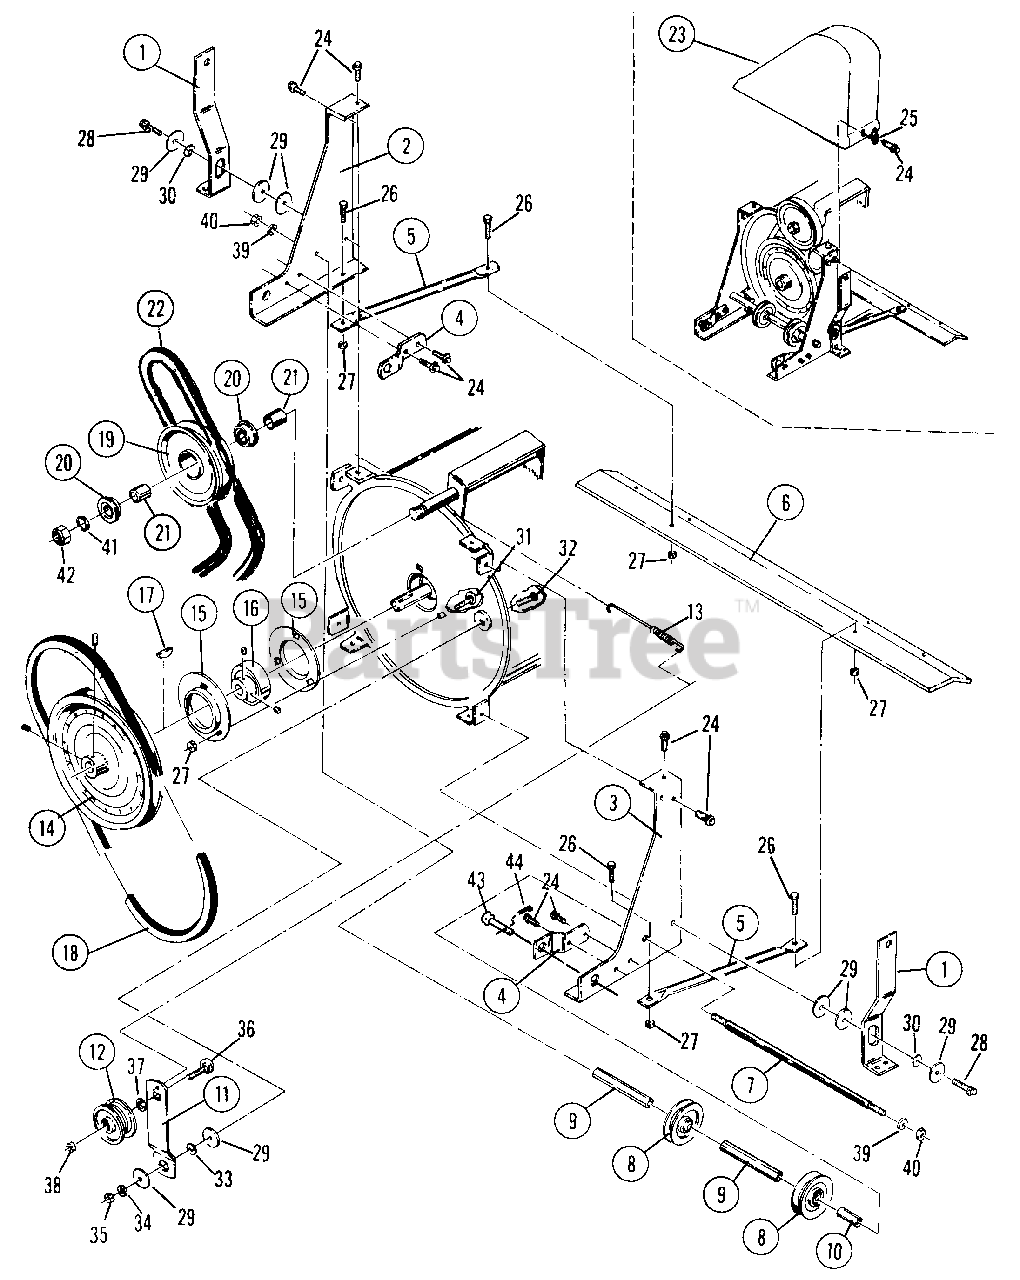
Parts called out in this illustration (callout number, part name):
1	LINK, Lift
2	BRACKET, Left Side Mounting
3	BRACKET, Right Side Mounting
4	BRACKET, Lower Mounting
6	BAR, Stiffener
7	ROD, Idler
8	IDLER, Belt
9	SPACER, (Long)
10	SPACER, (Short)
11	ARM, Idler
12	IDLER
13	SPRING, Idler
14	PULLEY, 8.36" O.D.
15	HOUSING, Bearing
16	BEARING
17	KEY, 3/16 x 7/8" Woodruff
18	BELT, Blower (short)
19	SHEAVE, Reduction
20	BEARING
21	SPACER, Bearing
22	BELT, Carrier to Blower (Long)
23	COVER, Belt Guard
24	SCREW, 5/16-18x5/8 Self tap
25	WASHER, 3/8 SAE (Flat)
26	BOLT, 5/16-18x5/8 Flange Lock
27	LOCKNUT, 5/16 Hex Flange
28	SCREW, 5/16-18x1 Self tap
29	WASHER, 5/16" x 1-1/4" x 3/32" Flat
31	BOLT, 5/16Cx3/4 S.N. Carriage
32	BOLT, 5/16-18x1 S.N. Carriage
33	SPACER
34	LOCKWASHER, 5/16 Split
35	NUT, 5/16-18
36	BOLT, 3/8-16x1-1/2 S.N. Carriage
37	WASHER, 7/16 SAE
38	LOCKNUT, 3/8-16 Hex
39	LOCKWASHER, 3/8 Split
40	NUT, 3/8-16
41	WASHER
42	LOCKNUT, 5/8-18 Jam
43	PIN, Clevis
44	HAIR-PIN
